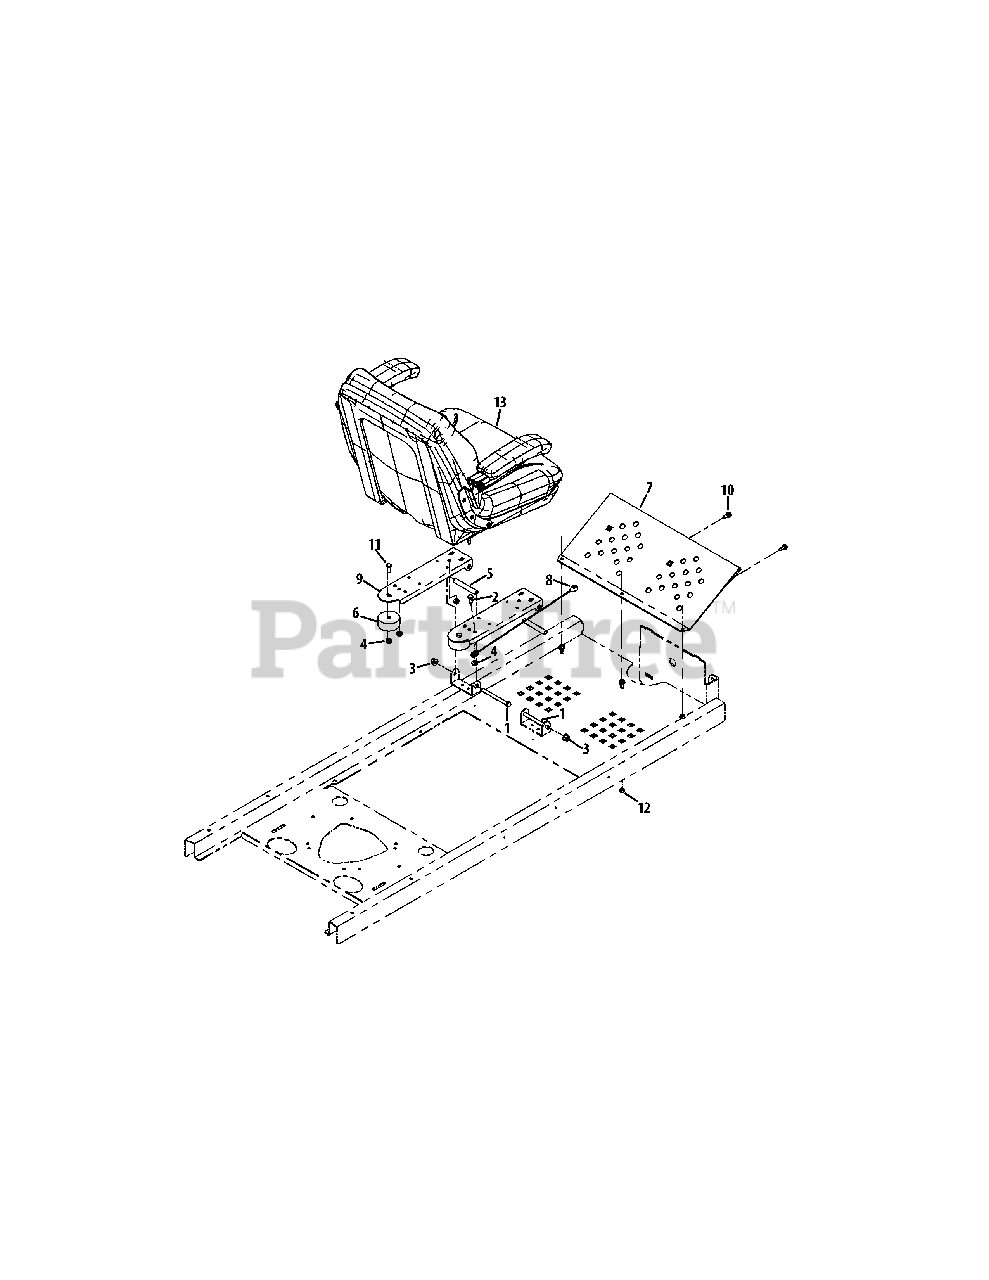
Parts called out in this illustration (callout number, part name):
1	Hex Cap Screw, 3/8-16 x 4.00
2	Hex Cap Screw, 5/16-18 x 3/4
3	Flange Lock Nut, 3/8-16
4	Flange Lock Nut, 5/16-18
5	Spacer, .370 ID x .500 x 3.45
6	Bumper, 2.50 x 1.13
7	Foot Rest Bracket
8	Lift Cable
9	Seat Mounting Bracket
10	Self Tapping Screw 5/16-18 x .750
11	Hex Cap Screw, 5/16-18 x .75
12	Nylock Nut, 5/16-18
13	Seat
